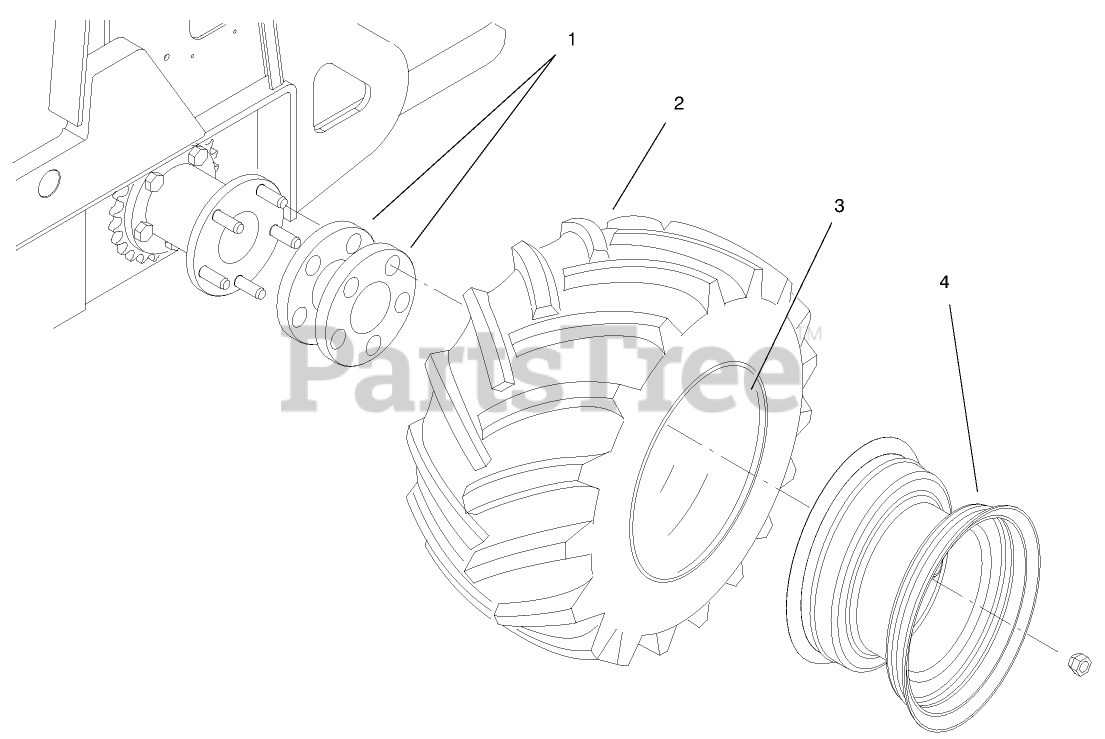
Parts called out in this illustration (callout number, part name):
1	Spacer-Wheel
2	Tire
3	TUBE-TIRE
4	WHEEL
